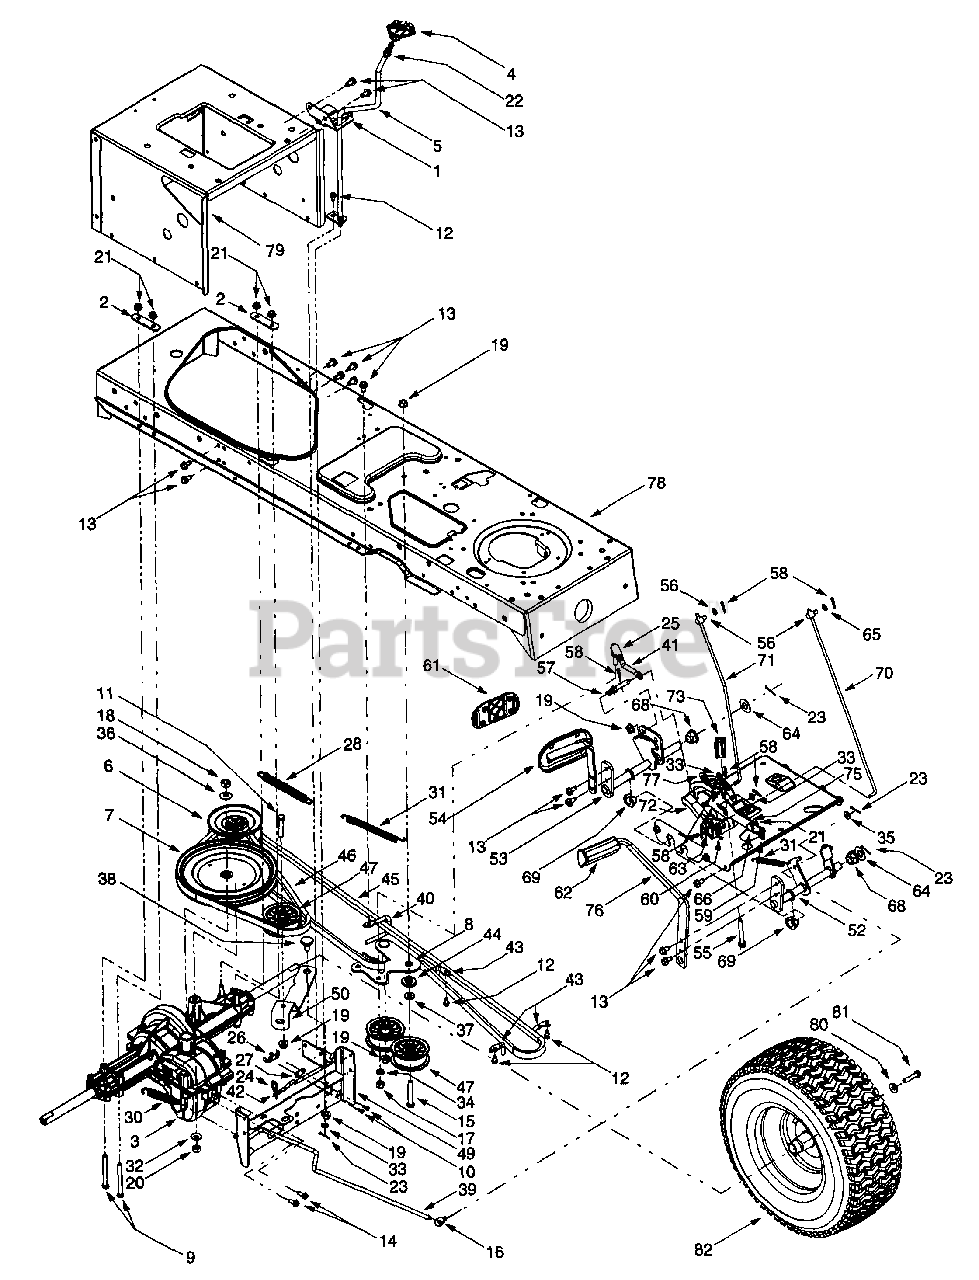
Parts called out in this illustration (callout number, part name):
1	Shift Lever Bracket
3	Single-speed Transmission Assembly
4	Shifter Knob
5	Shift Lever
6	Variable-speed Pulley Assembly
7	Transmission Pulley, 8.5 x .5-36
8	Double-idler Bracket
9	Hex Cap Screw, 5/16-18 x 3
10	Self Tapping Screw, #8-18 x .5
11	Hex Cap Screw, 3/8-16 x 1.75
12	Self Tapping Screw, 1/4-20 x .5
13	Self Tapping Screw, 5/16-18 x .625
14	Self Tapping Screw, 1/4-20 x .75
15	Hex Cap Screw, 3/8-16 x 2.25
16	Ferrule, 5/16-18
17	Hex Nut, 3/8-24
18	Hex Nut, 7/16-20
19	Flange Lock Nut, 3/8-16
20	Hex Nut, 3/8-16
21	Flange Lock Nut, 5/16-18
22	Jam Nut, 3/8-16
23	Cotter Pin
24	Internal Cotter Pin
25	Ball Joint, 3/8-24
26	Short Spring Switch
27	Insulator Nut Plate
28	Extension Spring, .62 Dia. x 6.12
30	Extension Spring, .59 OD x 4
31	Extension Spring, .50 Dia. x 6.37
32	Bell Washer, .401 x .87 x .063
33	Flat Washer, .385 x .62 x .063
34	Lock Washer, 3/8
35	Flat Washer, 5/16
36	Bell Washer, .45 x 1.0 x .602
37	Flat Washer, .407 x .812 x .135
38	Shoulder Screw, .625 x .217
39	Brake Rod
40	Belt Guard
41	Idler Adjustment Rod, 3/8
42	Shift Rod
43	Belt Guard Rod
44	Shoulder Spacer, .38 ID
45	Variable-speed Belt
46	Drive Belt
47	Flat Idler, 2.75 OD
52	Brake Control Assembly
53	Speed Control Assembly
54	Drive Pedal Assembly
55	Self Tapping Screw, 5/16-18 x 2.5
56	Ferrule, 1/4-20
57	Pin, 3/8-16 x 2.43
58	Cotter Pin
59	Compression Spring, .34 OD x 1.0
60	Extension Spring, .50 OD x 1.41
61	Drive Pedal Pad
62	Brake Pedal Pad
63	Flat Washer, .281 x .5 x .0625
64	Flat Washer, .64 x 1.24 x .06
65	Flat Washer, .344 x .062 x .03
66	Shoulder Screw, .437 x 1.62
68	Hex Flange Bearing
69	Split Hex Flange Bearing
70	Cruise Control Rod
71	Brake Lock Control Rod
72	Cruise Latch
73	Spacer, 5/16 x 1.54
75	Lockout Bracket
81	Hex Cap Screw, 5/16-24 x .75
